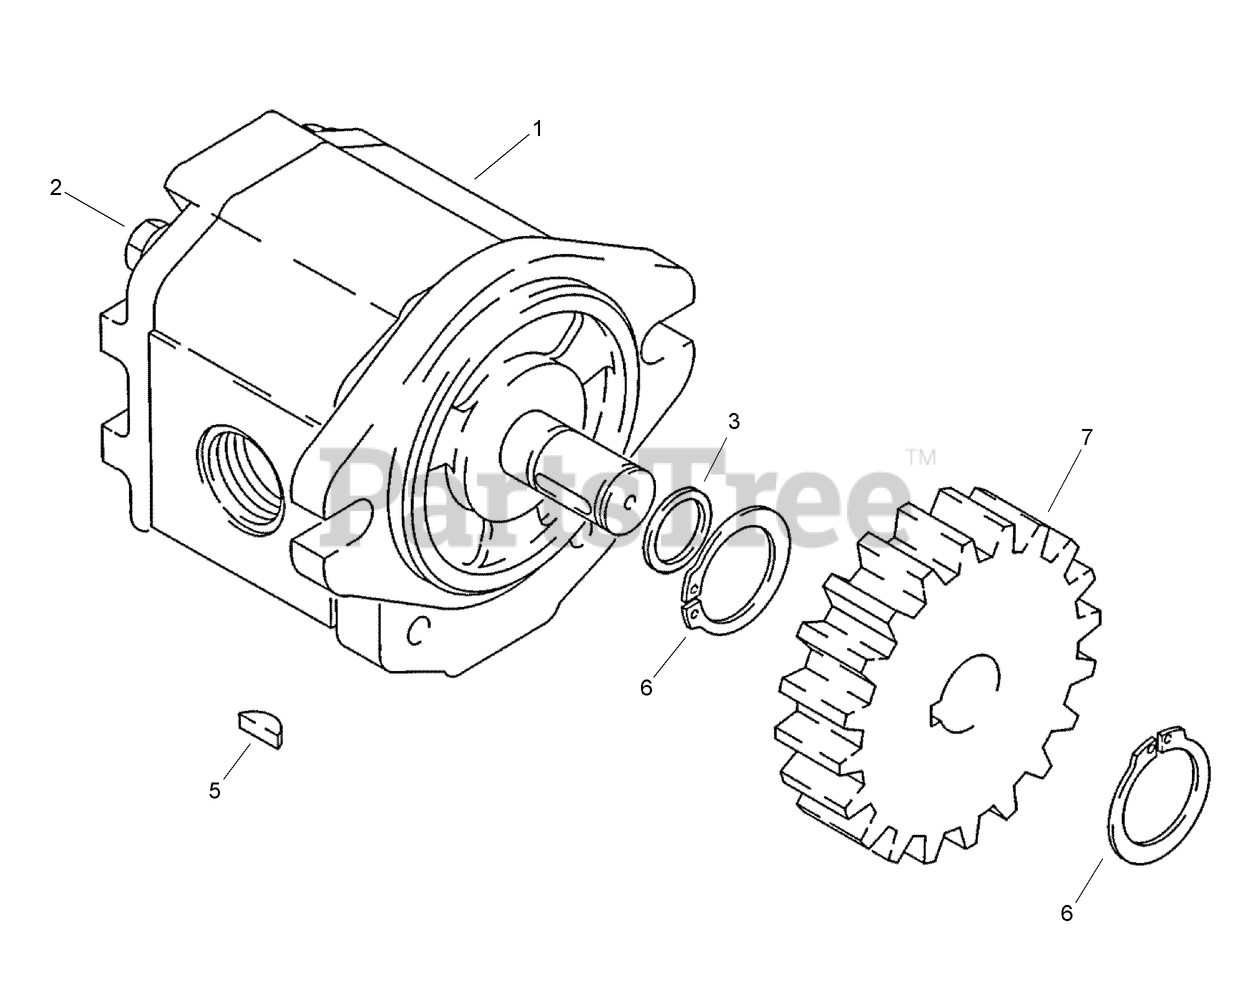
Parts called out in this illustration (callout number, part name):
1	GEAR MOTOR ASM
2	BOLT - Hex, Special
3	SEAL - Shaft
5	KEY - Gear
6	RING - External Retaining, No. 68, External, 41/64 inch ID
7	GEAR-MOUNTING, DRIVE
